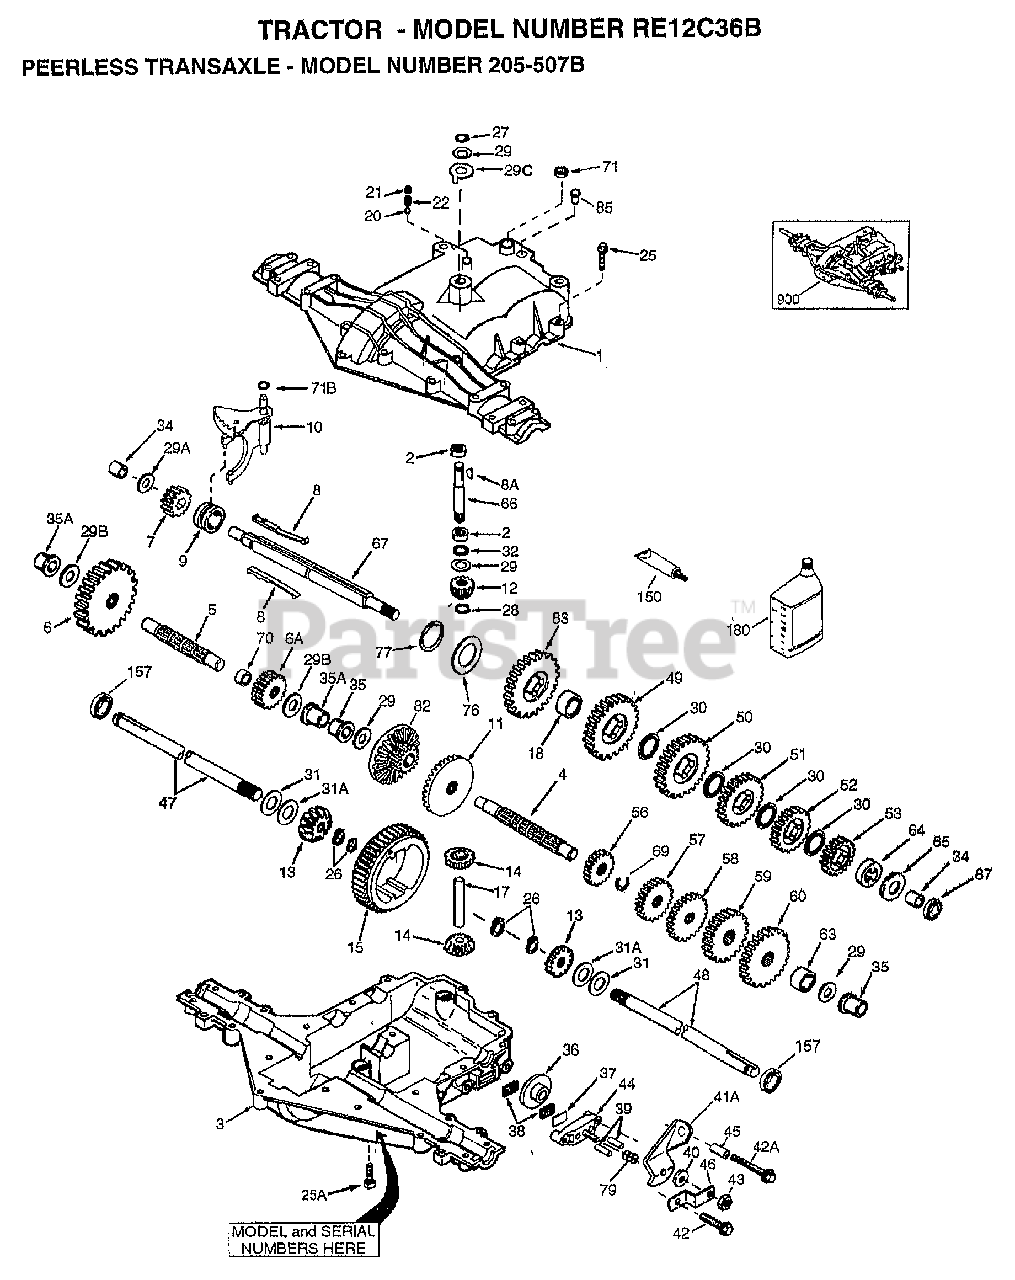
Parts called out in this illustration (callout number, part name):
1	TRANSAXLE COVER
2	NEEDLE BEARING 5/8" ID
3	TRANSAXLE CASE
4	COUNTERSHAFT
5	OUTPUT SHAFT
6	SPUR GEAR (38 TEETH)
6A	SPUR GEAR (15 TEETH)
7	SPUR GEAR (11 TEETH)
8A	KEY, WOODRUFF
9	COLLAR, SHIFTER
10	SHIFT ROD & FORK
11	BEVEL GEAR (30 TEETH)
12	INPUT BEVEL PINION (13TEETH)
13	BEVEL GEAR (13 TEETH)
14	BEVEL PINION (13 TEETH)
15	RING GEAR (43 TEETH)
18	SPACER, NEUTRAL
20	BALL STEEL, 5/16" DIA.
21	SCREW, 3/8-16 X 3/8"
25A	SCREW 1/4-20 X 1-3/8"
26	RING RETAINER
27	RING, RETAINER
28	RETAINING RING
29	WASHER THRUST
29B	WASHER THRUST
29C	P/N CONFLICT - CHECK WITH SUPPLIER
30	WASHER THRUST
31A	FLAT WASHER
32	OIL SEAL 5/8"
34	BUSHING 9/16"
35	FLANGED BUSHING 5/8" ID
35A	FLANGED BUSHING 3/4"
37	PLATE BRAKE PAD
41A	BRAKE LEVER
42A	SCREW, 1/4-20 X 2-1/4
43	LOCKNUT 5/16-24
44	HOLDER BRAKE PAD
46	BRKT BRAKE LEVER
49	SPUR GEAR (29 TEETH)
50	SPUR GEAR (23 TEETH)
51	SPUR GEAR (19 TEETH)
52	SPUR GEAR (16 TEETH)
53	SPUR GEAR (15 TEETH)
56	SPUR GEAR (11 TEETH)
57	SPUR GEAR (17 TEETH)
58	SPUR GEAR (21 TEETH)
59	SPUR GEAR (24 TEETH)
60	SPUR GEAR (25 TEETH)
66	INPUT SHAFT
67	SHIFTER & BRAKE SHAFT
69	RETAINING RING
70	SPACER .890
71	SEAL SQUARE CUT
76	WASHER, THRUST
77	INVERTED RETAINING RING
82	BEVEL & SPUR GEAR (30 & 13 TEETH)
83	SPUR GEAR (27 TEETH)
85	OIL FILL PLUG
87	OIL SEAL 9/16"
150	LIQUID GASKET RTV SILICONE
157	OIL SEAL 3/4"
180	GEAR OIL 80W90
